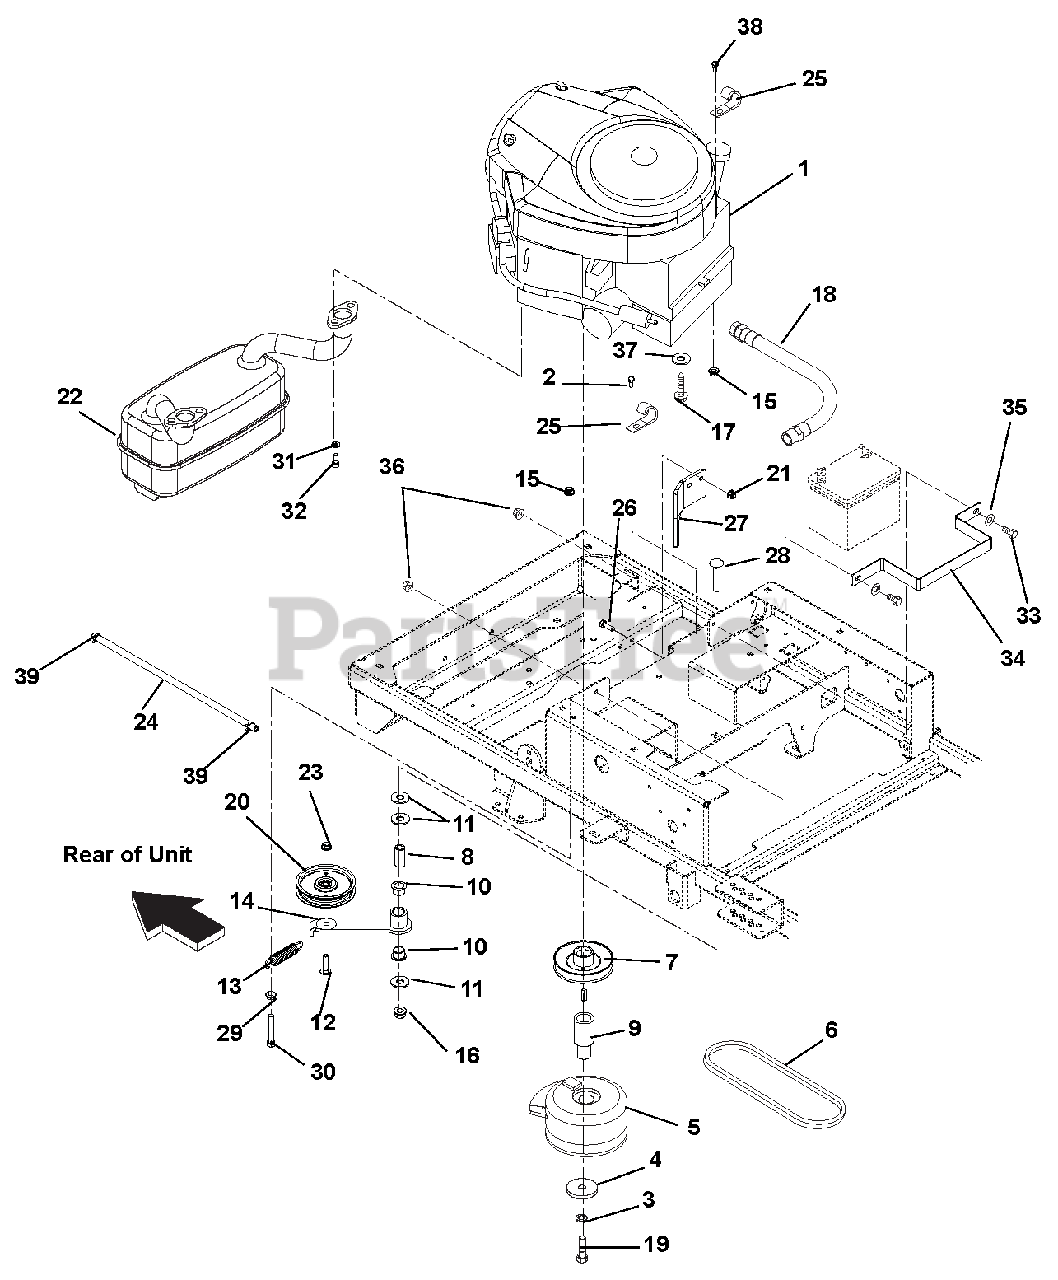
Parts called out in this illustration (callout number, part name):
1	ENGINE, KAWASAKI FR651V
2	@SCR-TAP .25-20X.37 HWH YWZ TR
3	@WSHR-LK .44X.109 REG YWZC
4	WSHR-FL-STL .469X2.00X.25 YWZC
5	CLUTCH, MS
6	V-BELT, HA-WRAPPED
7	PLY-V 4.5X1.5 AB SECTION W/KEY
8	BSHG-SLV .500X.750X1.560
9	EXT-CRANKSHAFT LOWER
10	BSHG-FLG 0.75X0.875X.625X1.125
11	@WSHR-FL-STL.563X1.38X.109YWZC
12	@BLT-RDHDSQNK .38-16X1.50 G5YZ
13	SG-TENS .105X.812X3.88 WLD 15
14	WMT, GROUND DRIVE IDLER ARM
15	@NUT-LK-NYL-FLG .38-16 YWZC
16	@NUT-LK-TOP-FLG .50-13 YWZC
17	BLT-HEX.38-16X1.25FTHG5 EP30YZ
18	OIL DRAIN HOSE
19	BLT-HEX .44-20X4.50 GR8 YWZC
20	ASM, 4" IDLER (.75 WIDE)
21	@NUT-LK-NYL-FLG .31-18 YWZC
22	MUFFLER, TWIN
23	@NUT-LK-TOP-FLG .38-16 YWZC
24	HOSE, .25 LOW-PERM BULK GAS
25	J-CLAMP
26	@BLT-HEX .31-18X1.00 GR5 YWZC
27	CLUTCH STOP
28	@BLT-RDHDSQNK .50-13X2.50 G5YZ
29	@NUT-SPNLK-FLG .375-16 YWZC
30	@BLT-HEX .38-16X2.50 GR5 YWZC
31	@WSHR-LK .31X.078 REG YWZC
32	SCR-CAP .31-18X.75 S/HD
33	@BLT-HEX .25-20X.75 GR5 YWZC
34	BRKT, BATTERY HOLD DOWN
35	@WSHR-FL-STL.281X.62X.065 YWZC
36	NUT-KEPS .250-20
37	@WSHR-FL-STL.406X.812X.065 YWZ
38	@BLT-HEX .38-16X.75 GR5 YWZC
39	CLAMP, FUEL LINE
